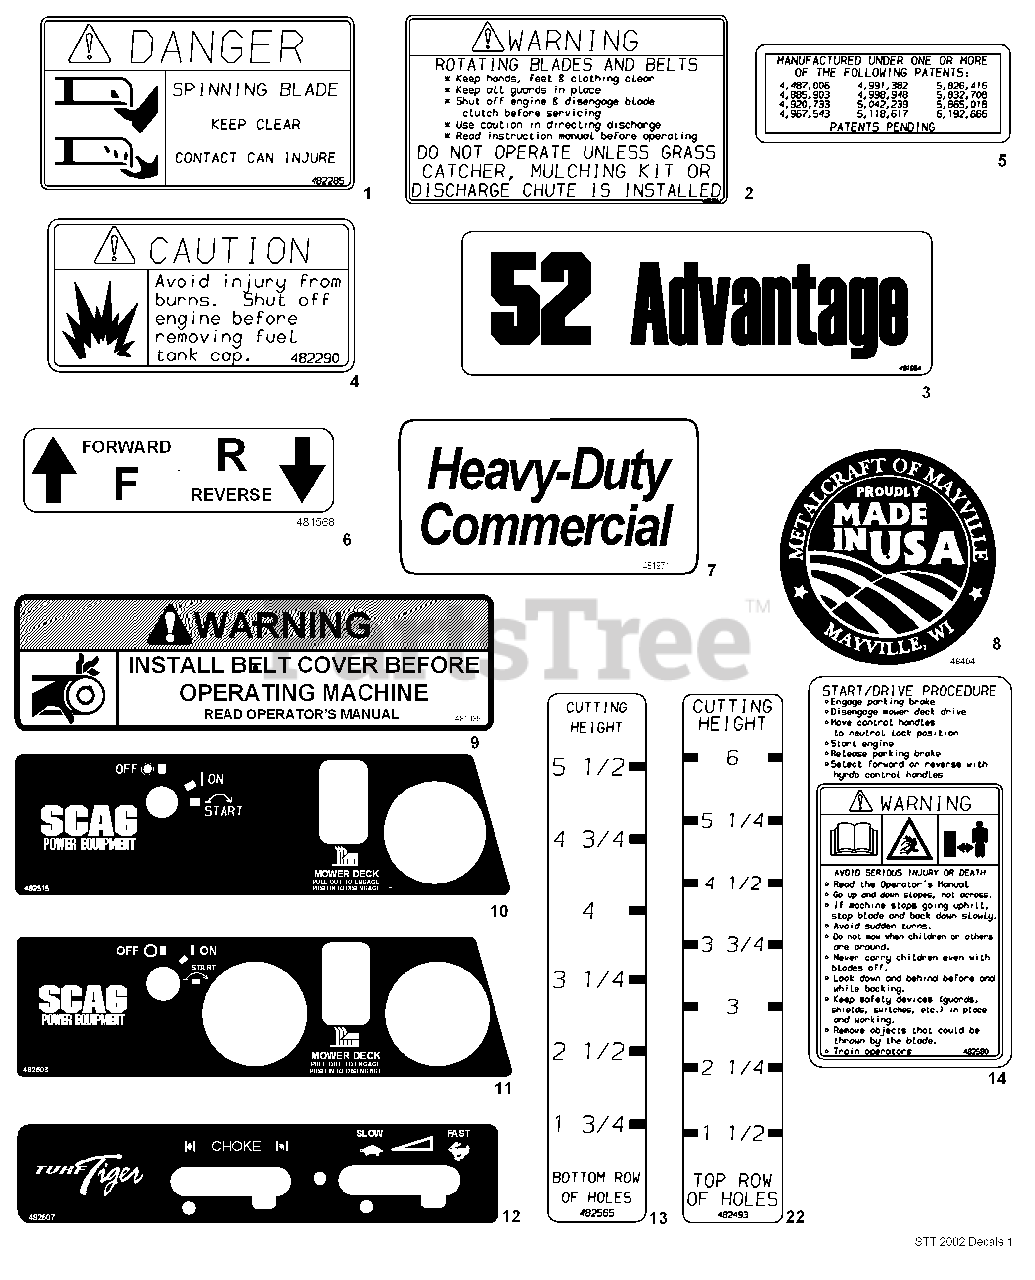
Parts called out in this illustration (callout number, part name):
1	Decal, Danger-Spining Blades
2	Decal, Warning-Rotating Blades
3	Decal, 72 Advantage
4	Decal, Fuel Tank
5	Decal, Patents
6	Decal, Traction Control
7	Decal, Heavy Duty Commercial
8	Decal, MetalCraft-Made In USA
9	Decal, Belt Cover
10	Decal, Instrument Panel-Upper
11	Decal, Instrument Panel-Upper
12	Decal, Instrument Panel-Lower
13	Decal, Cutting Height - Lower
14	Decal, Start/Drive Procedure
22	Decal, Cutting Height - Upper
